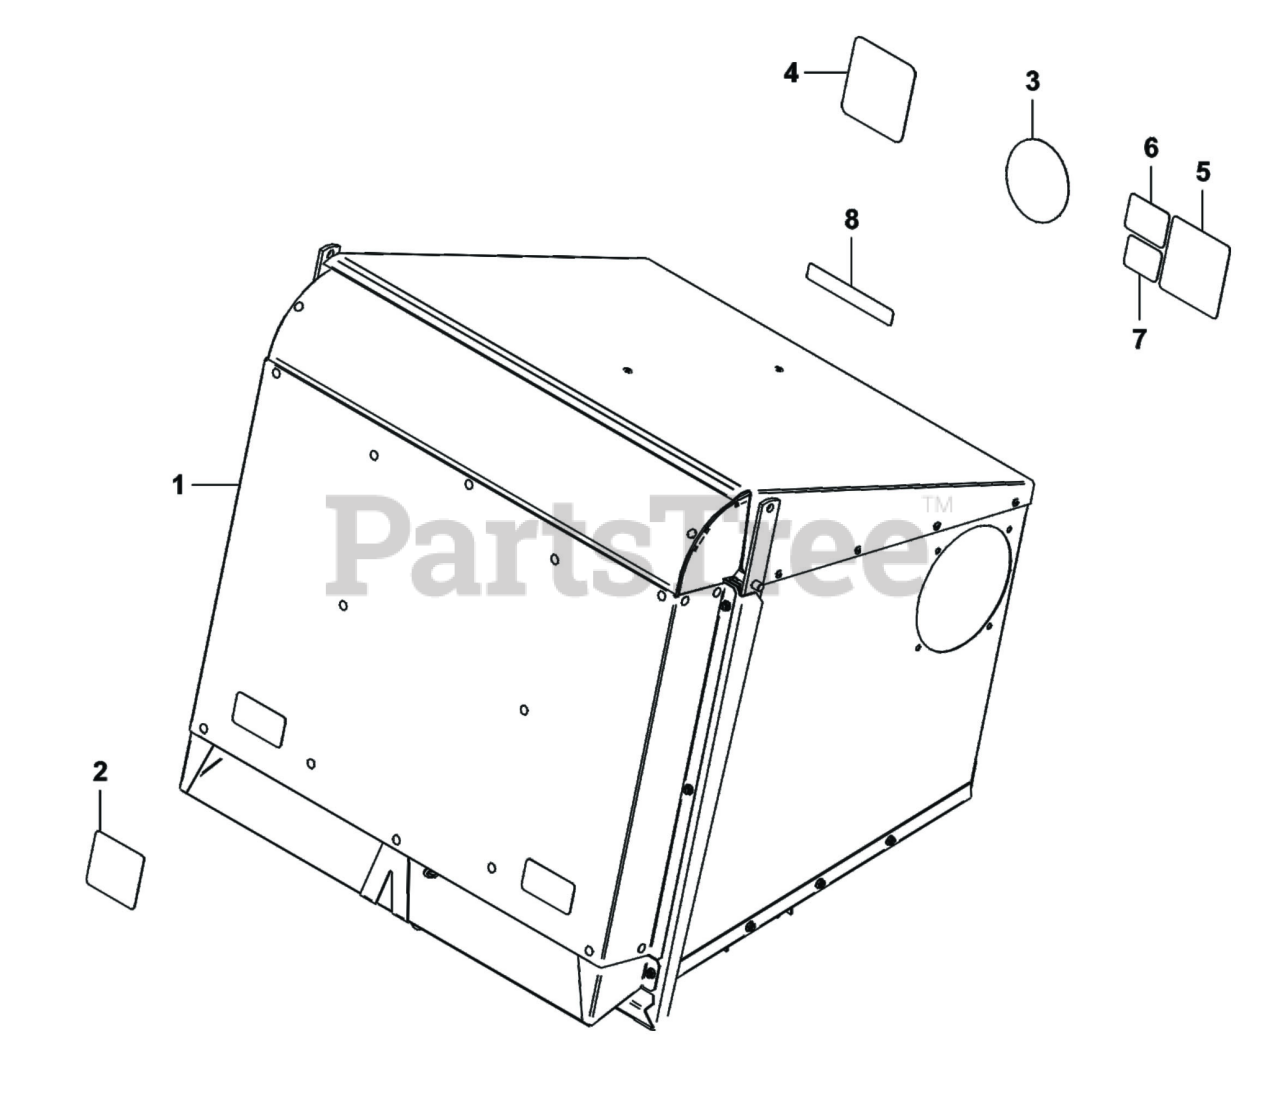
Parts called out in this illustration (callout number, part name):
1	12 CU. FOOT BOX ASSEMBLY
1	6512 BOX ASSEMBLY
3	BUILT IN USA LABEL
4	Decal/Operation
5	LABEL-WARNING
6	DECAL-TUBE WEAR
7	DECAL-WARNING
